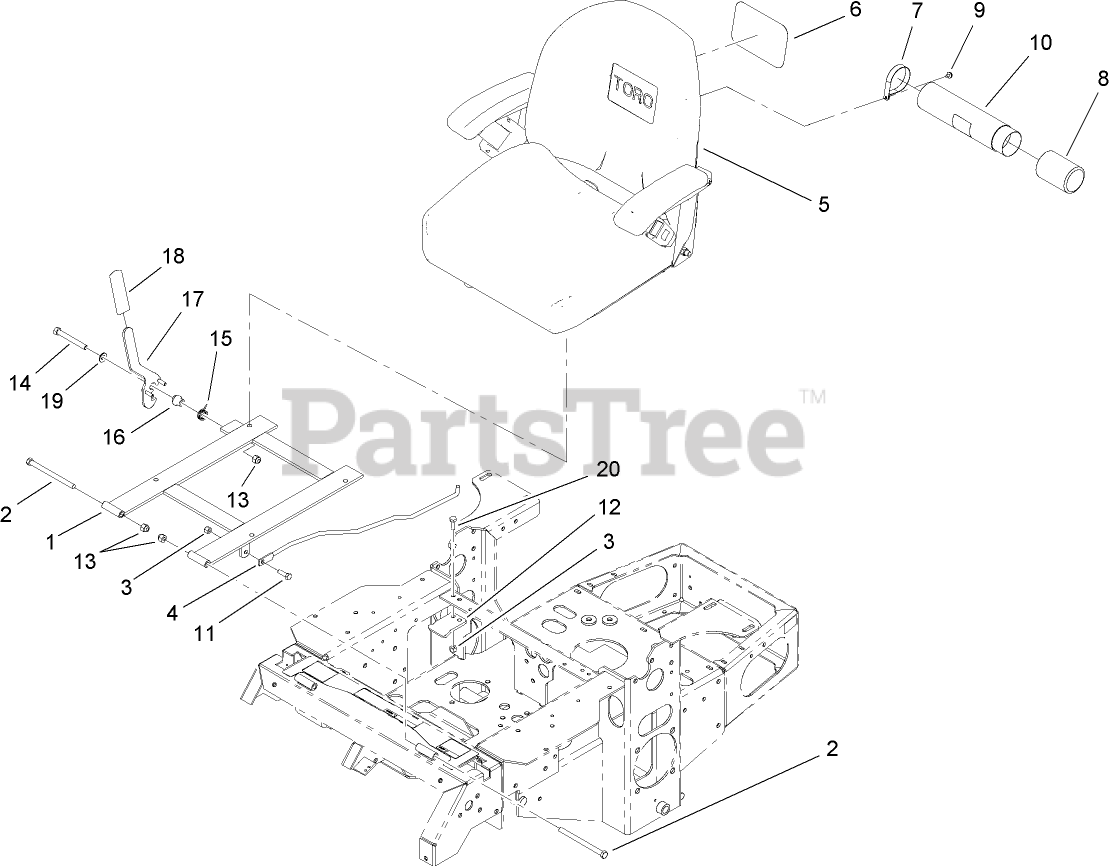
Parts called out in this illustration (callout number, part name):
1	SEAT SUPPORT FRAME ASM
2	SCREW-HH
3	NUT-LOCK, NI
4	ROD-RETAINER, SEAT
5	SEAT ASM
6	DECAL
7	CLAMP-R
8	CAP-HOUSING
9	SCREW-HWHTF
10	TUBE-MANUAL
11	SCREW-HH
12	CATCH-LATCH, SEAT
13	NUT-LOCK, NI
14	SCREW-HH
15	SPRING-TORSION
16	BUSHING-LATCH, SEAT
17	LATCH ASM
18	GRIP-LEVER
19	WASHER-FLAT
20	SCREW-HH
